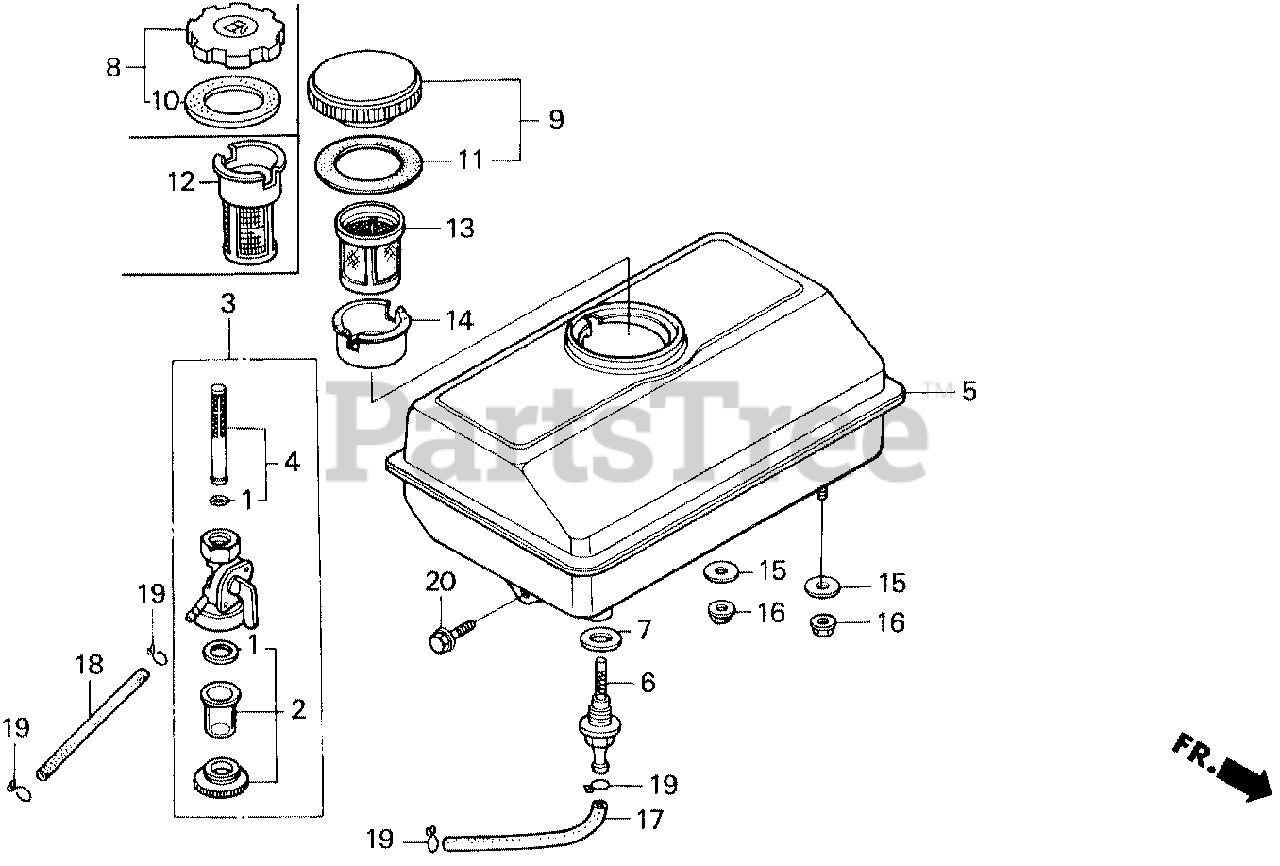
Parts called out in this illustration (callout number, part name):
5	TANK, FUEL *NH31* (MCKINLEY WHITE)
6	JOINT, FUEL TANK
7	O-RING (13.5X1.5) (ARAI)
8	CAP, FUEL FILLER
10	GASKET, FUEL FILLER CAP
16	NUT, FLANGE (6MM)
17	BULK HOSE, FUEL (4.5X3000) (4.5X55)
19	CLIP, TUBE (B8)
20	BOLT, FLANGE (6X14)
